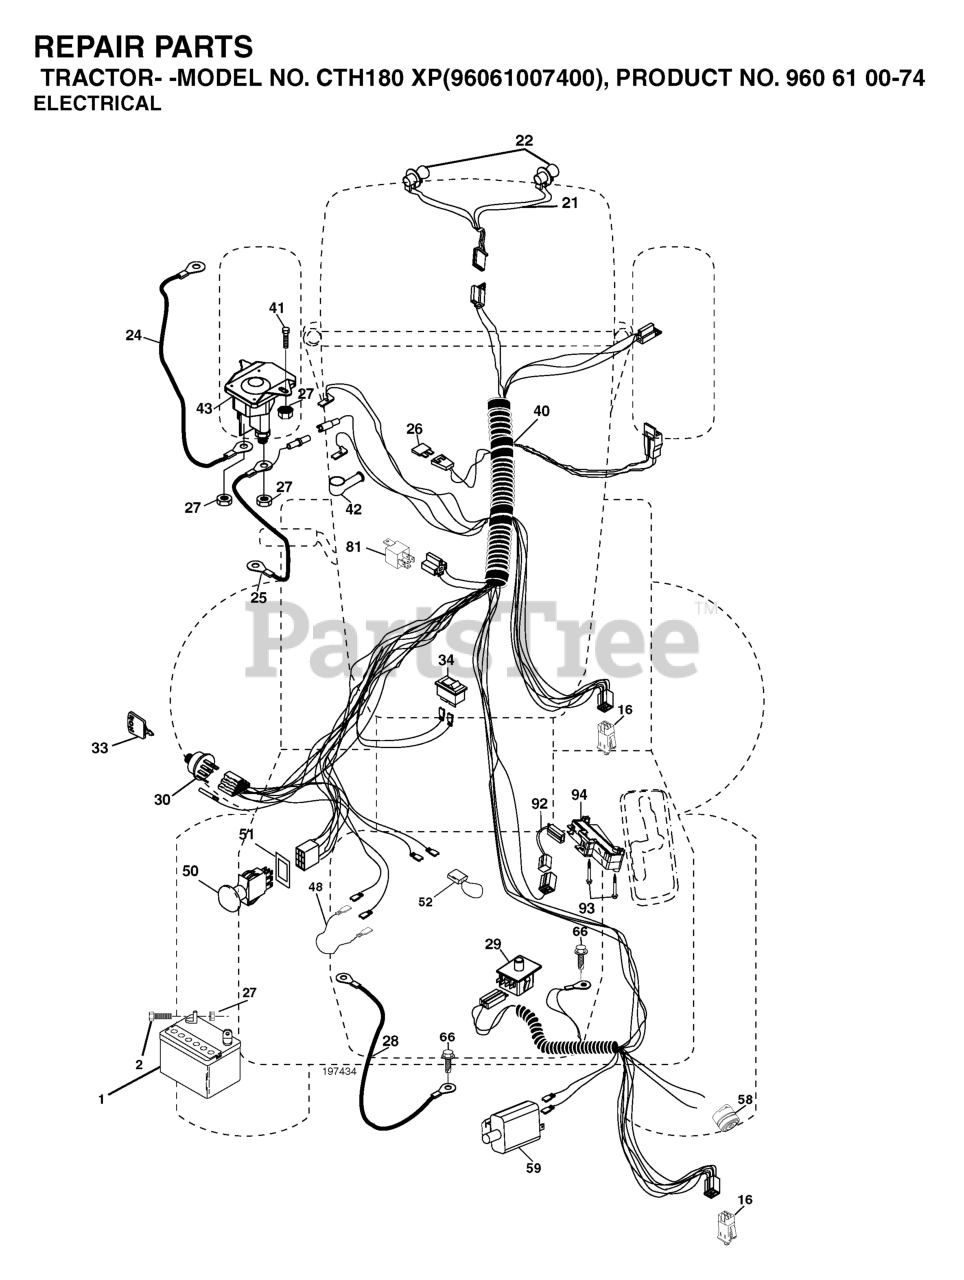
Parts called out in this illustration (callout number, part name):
1	BATTERY 12V .35 AMP
2	BOLT.HEX.1/4.X.3/4.DICHROMATE
16	SWITCH INTERLOOK PUSH-IN
21	HARNESS.W/LIGHT SOCKET
24	BATTERY CABLE GT
25	CABLE BATTERY
26	FUSE 20AMP
27	NUT
28	CABLE GROUND
29	SWITCH.SEAT.DP W/RAMPS
30	SWITCH.IGN.DELTA.W.LGH.ROS
33	KEY MLD GEN DELTA
40	RP HARNESS.IGN.ELECT.REG.CRD
41	BOLT
42	TERMINAL COVER
43	SOLENOID.W/BRASS.PLUNGER
48	ADAPTER.AMMETER
50	RP.PTO.SWITCH.8 TERMINAL.BLACK
51	FRAME RETAINING RING
52	WIRE PROTECTION LOOP
58	BUZZER
59	.WITCH.FULL BAGGER.INDICATOR
81	RELAY.ASSY.T
92	HARNESS.PIGTAIL.CONSLE
93	SCREW.PLASTITE
94	MODULE.REVERSE.ROS
